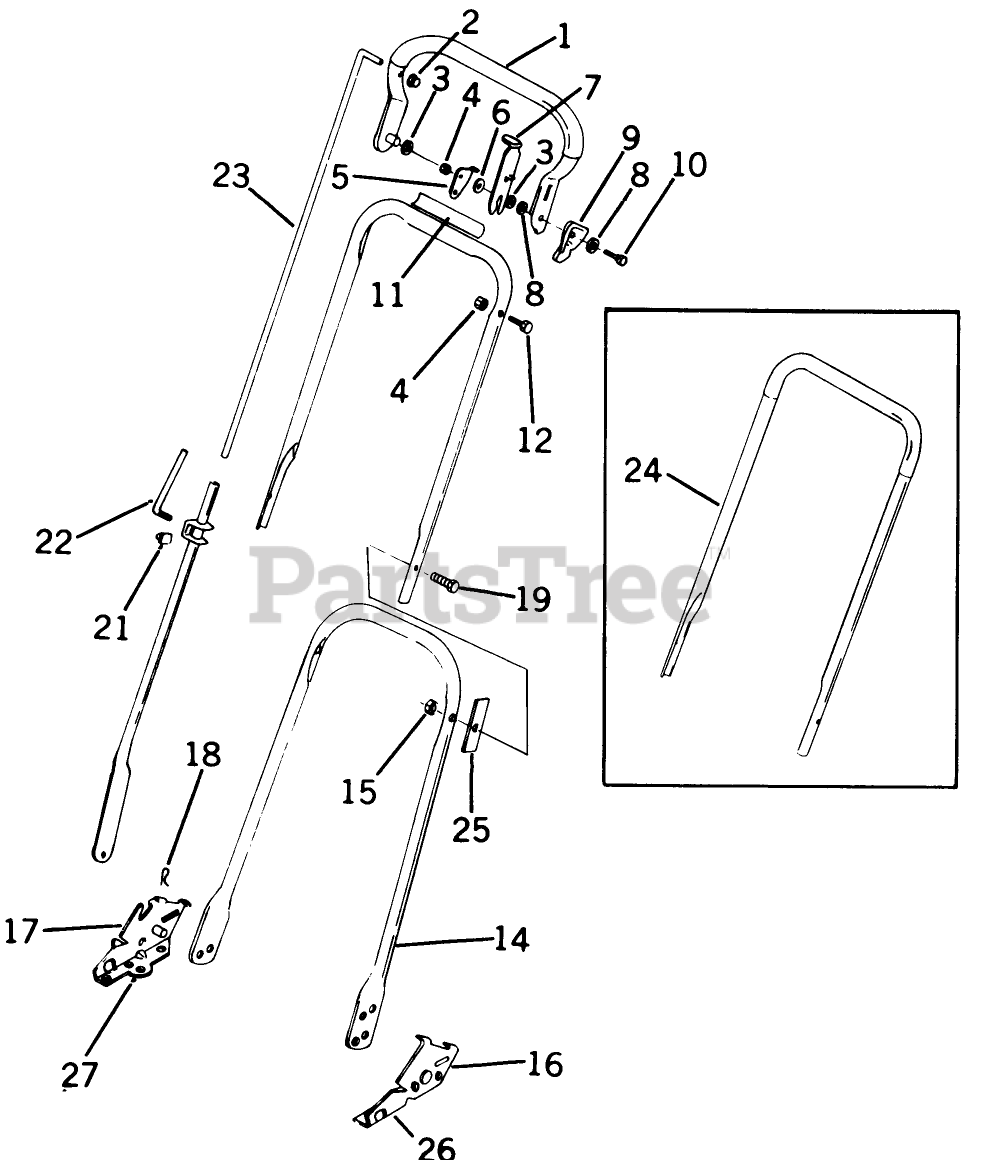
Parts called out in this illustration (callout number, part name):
3	WASHER M
4	LOCKNUT E
5	HANDLE STOP
6	WASHER
7	LEVER LOCKOUT
10	BOLT PIONEER
12	SCREW-HANDLE STOP
15	LOCKNUT E
17	HANDLE BRACKET
18	HAIR PIN
19	SCREW - USE 137-3042
23	ROD CONTROL
